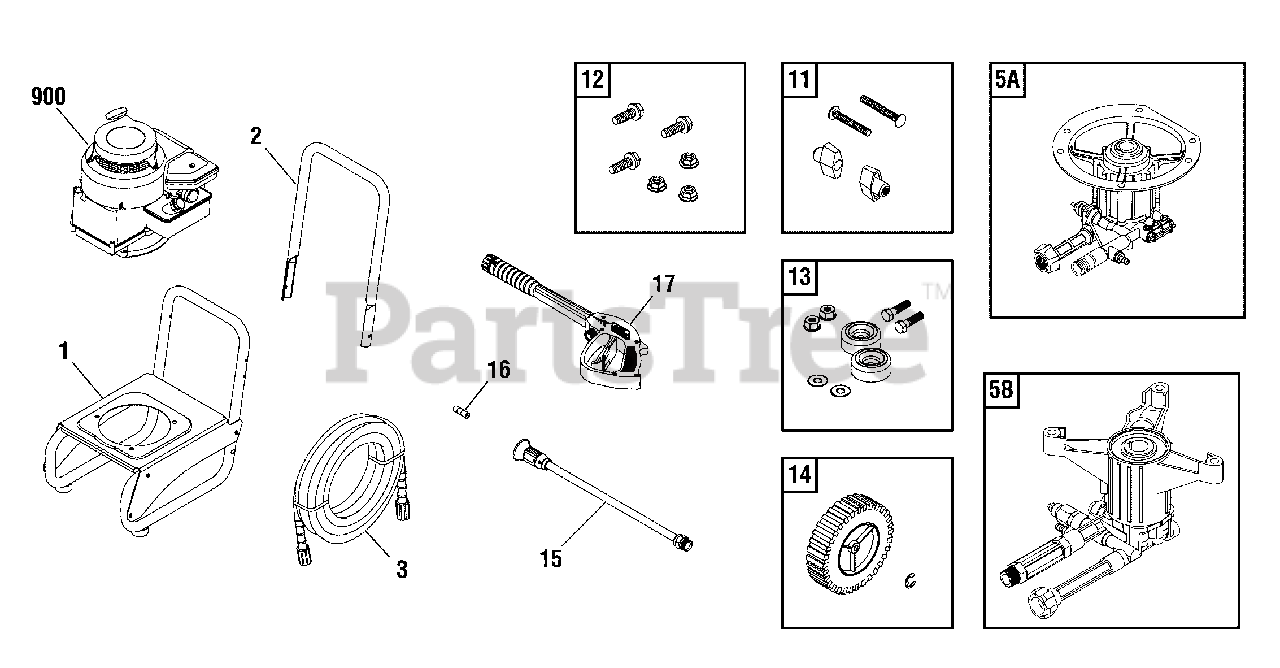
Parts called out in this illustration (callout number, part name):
1	BASE, w/ Mounts
3	HOSE
5A	ASSY, Pump
11	KIT, Fastening Handle
12	KIT, Pump/Engine Mounting Hardware
13	KIT, Vibration Mount
17	GUN
900	* ENGINE
